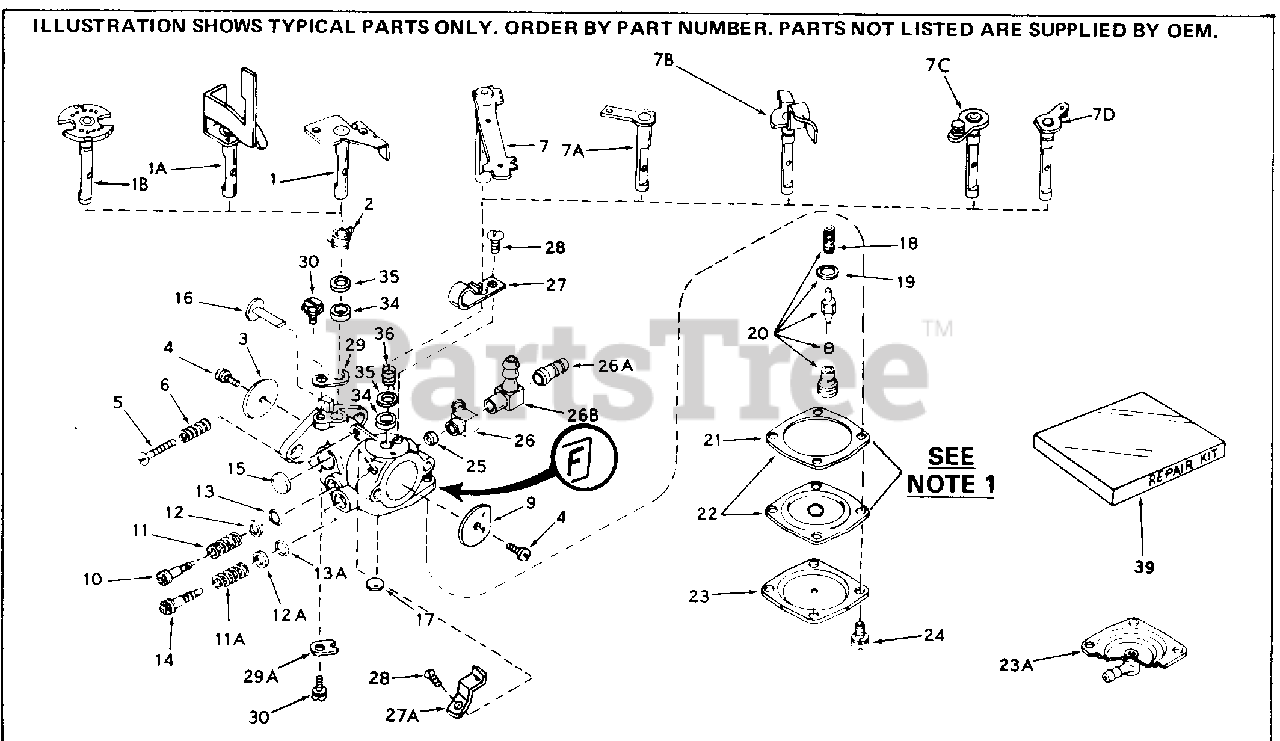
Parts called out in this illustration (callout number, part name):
1	"Shaft & Lever Assy., Throttle
2	Spring, Throttle return
3	Shutter, Throttle
4	Screw, Throttle & Choke shutter
5	Screw, Idle regulating
6	Spring, Idle regulating
7A	Shaft & Lever Assy., Choke
9	Shutter, Choke
10	Screw, Idle adj.
11	Spring, Adj. screw
11A	Screw, Adj. screw
12	Washer, Adj. screw
12A	Washer, Adj. screw
13	"O" Ring, Adj. screw
13A	"O" Ring, Adj. screw
14	Screw, Main adj. (.0225 dia. hole)
15	Plug, Welch
17	Plug, Welch
18	Spring, Valve
19	Gasket, Valve seat
20	Inlet Needle, Seat, Gasket & Spring A ssy.
21	Gasket, Diaphragm
22	Diaphragm Assy.
23	Cover, Diaphragm
24	Screw, Cover
26B	Fitting, Fuel inlet
27	Spring, Detent
28	Screw, Detent spring
29	Retainer, Throttle shaft
30	Screw, Retainer
39	Repair Kit
